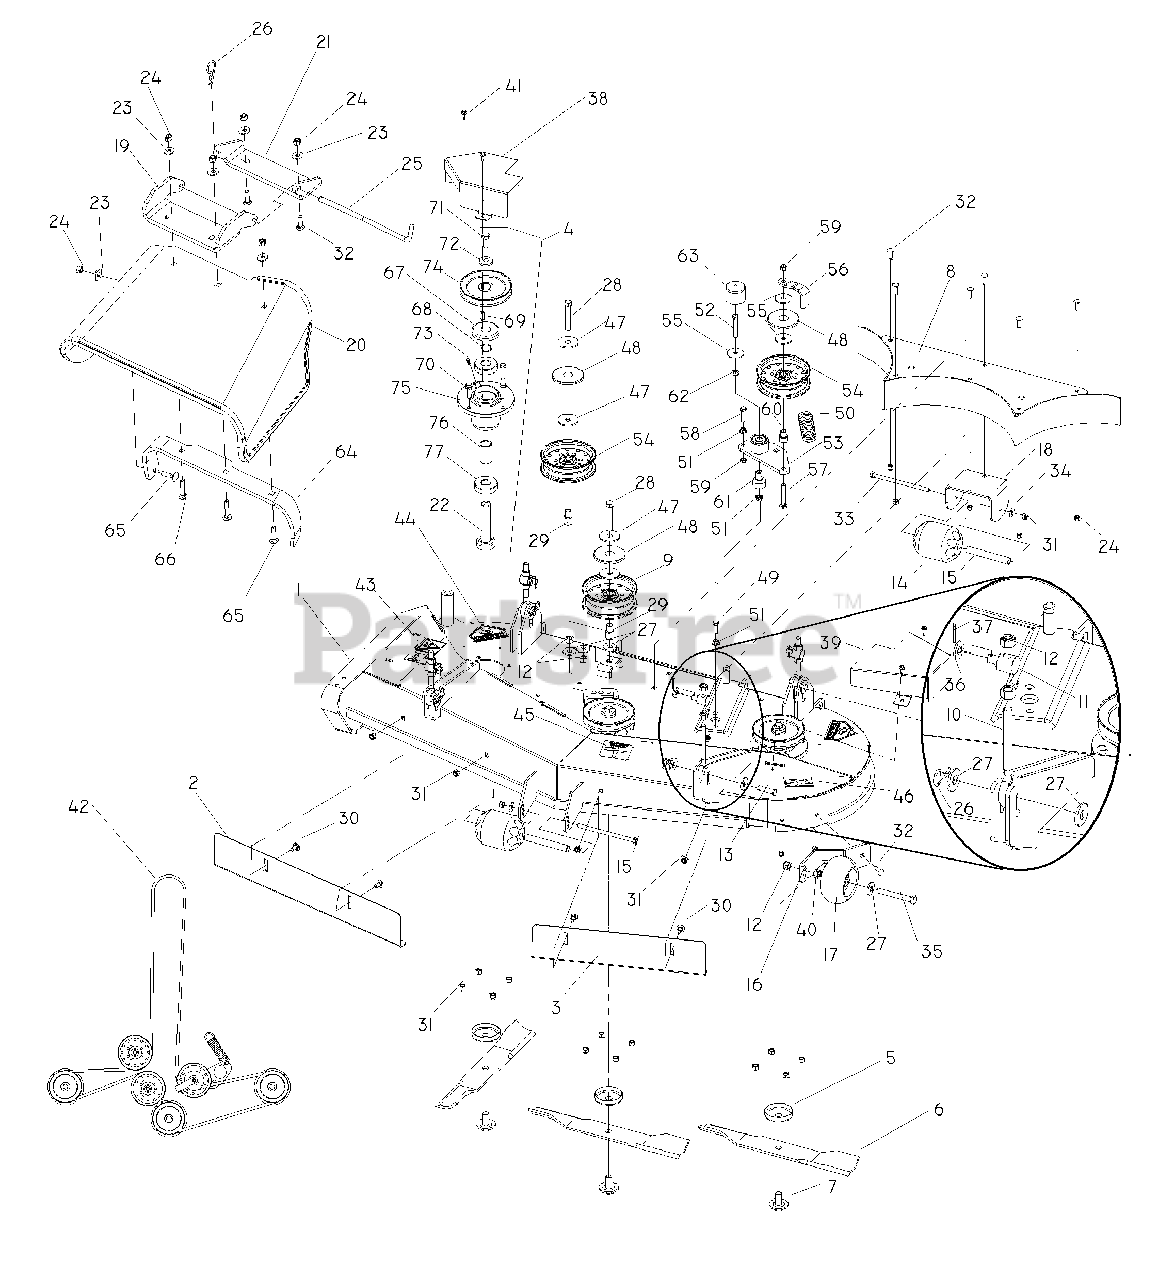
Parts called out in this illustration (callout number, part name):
1	DECK W/DECAL 52 KODIAK
2	BLOW-BY BAFFLE 52` LH
3	BLOW-BY BAFFLE 52` RH
4	SPINDLE ASM.
5	TRASH GUARD
6	BLD 52HFS HI LIFT FUS
7	BLADE BOLT/WASHER
8	W-BAFFLE WLDT.
9	IDLER PULLEY (TALL)
10	BOLT, EYE
12	NUT 1/2-13 HEX NYLOC ZD
13	CLEVIS PIN 1/2X1-3/4LG
14	ROLLER 3-3/4 DIA. X 4-1
15	BUSHING
16	BRACKET
17	GAUGE WHEEL
18	REAR CENTER ROLLER BKT 52 CLK
19	PIVOT BRKT RUBBER CHUTE
20	CHUTE, RUBBER DISCHARGE 52"
21	PIVOT BRACKET - DECK
22	SHAFT SHORT
23	WASHER 5/16 FLAT
24	NUT 5/16 NYLOC
25	DEFLECTOR PIN
26	PIN, COTTER 1 3/4
27	WASH USS FLAT 1/2
28	SCREW, 1/2C X 3 HEX CAP
29	SPACER - IDLER
30	RHSNB 3/8-16 X 3/4 GR5 ZD
31	NUT 3/8-16 NYLOC
32	RHSSNB 5/16C X 1.0
33	3/8-16 X 6-1/2 HHB GR8
34	WASHER 3/8 FLAT
35	HCS 1/2-13 X 4 GR 5 ZD
36	WASHER 1/2" FLAT
37	PIN COTTER 1/8 X 1 ZD
38	PULLEY GUARD RH BLACK
39	PULLEY GUARD 52 LH BLACK
40	NUT HEX 1/2
41	SCREW, TAP & DR #12-14 X 3/4
42	BELT-DECK, 52
43	DECAL, EURO SEVERING
44	DECAL, CPSC
45	DECAL, BELT ROUTING (18656)
46	DECAL, 52"
47	ISOLATOR WASHER
48	TOP DUST CAP
49	HCS 3/8C X 1
50	DECK SPRING
51	NUT 3/8C WHIZ
52	HCS 3/8C X 2 1/2
53	ARM-IDLER W/BRG
54	IDLER PULLEY
55	WASHER, 3/8 SPEC
56	GUIDE, BELT
57	RHSNB 3/8-16 X 2.75
58	HCS 3/8-16 X 1-1/2
59	NUT 3/8-16 HEX JAM
60	BUSHING, IDLER
61	PIVOT, BEARING
62	WASHER 3/8 SAE FLAT
63	CAP, VINYL
64	BRACKET, REINF - CHUTE
65	BOLT, CARRIAGE 5/16X1-1/4
66	RHSNB 5/16-18 X 1-1/2 GR 5 ZD
67	TRASH GUARD
68	HUB PULLEY SPACER
69	KEY - 1/4 X .88
70	HCS 3/8C X 1 1/2
71	1/2-20 UNF X 1 1/4 HHBLT
72	WASHER .525 X 1.375 X .25
73	ZERK, 3/16, DRIVE IN
74	METRIC PULLEY
75	DECK HUB MACHINED
77	BEARING - 6305 - 2RS
